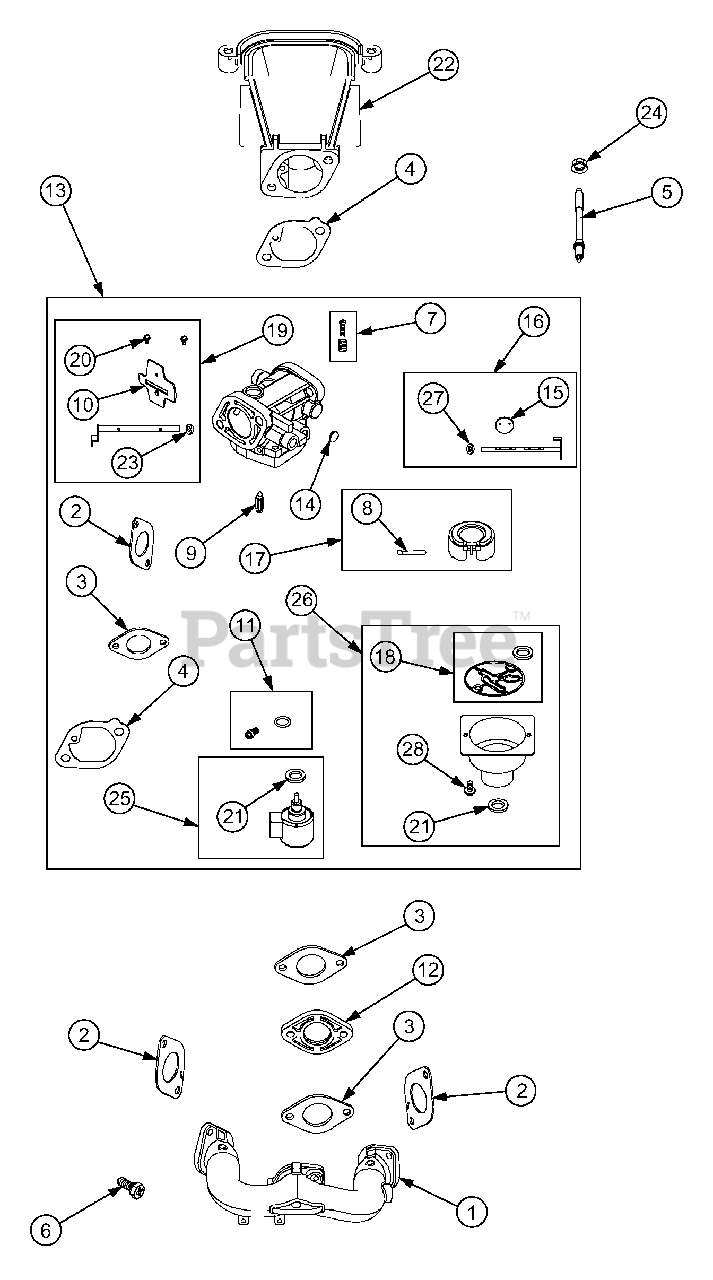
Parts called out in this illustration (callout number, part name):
1	Manifold, Intake
2	Gasket, Intake
3	Gasket, Intake
4	Gasket, Inake
5	Stud, Carburetor
6	Screw (Intake Manifold)
7	Kit, Idle Speed
8	Pin, Float
9	Valve, Float Needle
10	Valve, Choke
11	Jet, Main (Standard)
12	Spacer, Carburetor
13	Carburetor
14	Plug, Welch
15	Valve, Throttle
16	Kit, Throttle Shaft
17	Float, Carburetor
18	Gasket, Float Bowl
19	Kit, Choke Shaft
20	Screw (Choke Valve)
21	Washer, Sealing
22	Elbow, Intake
23	Seal, Choke/Throttle Shaft
24	Nut (Carburetor)
25	Solenoid, Fuel
26	Bowl, Float
27	Seal, Throttle Shaft
28	Screw (Float Bowl)
